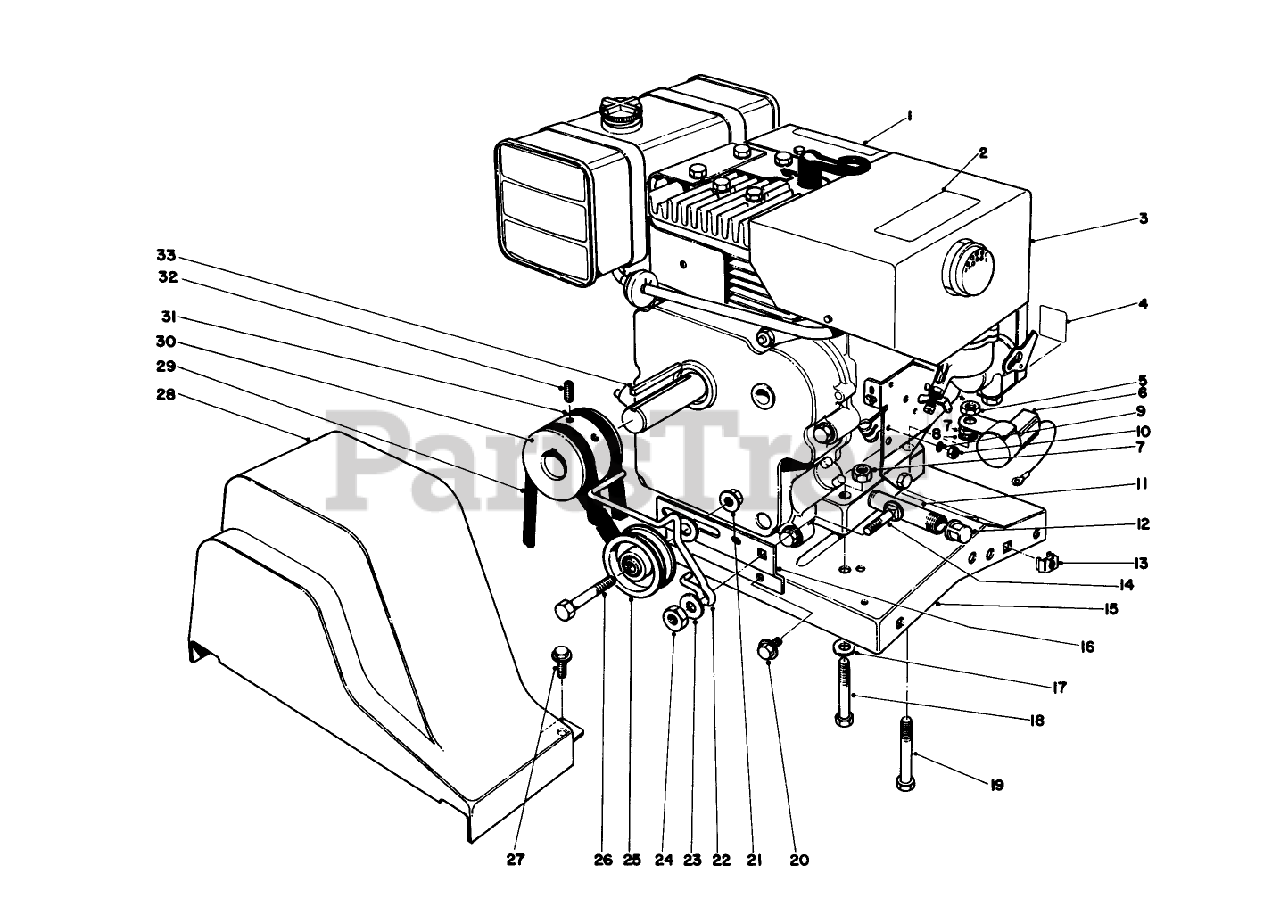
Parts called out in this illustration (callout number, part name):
5	NUT-HEX, SIDE DEFORM
6	INTERLOCK MODULE
7	NUT-LOCK, NI
8	WASHER-LOCK, INTERNAL
9	WASHER-LOCK/INT
10	NUT-LOCK
11	NIPPLE-PIPE
12	CAP-PIPE
14	SCREW-CARR
17	WASHER-PLAIN
18	SCREW-HH
19	Capscrew
20	SCREW-HHFTF
21	NUT-HHF, WHIZ
23	WASHER-FLAT
26	SCREW-HH
27	SCREW-HWH
29	V-BELT
31	V-BELT
